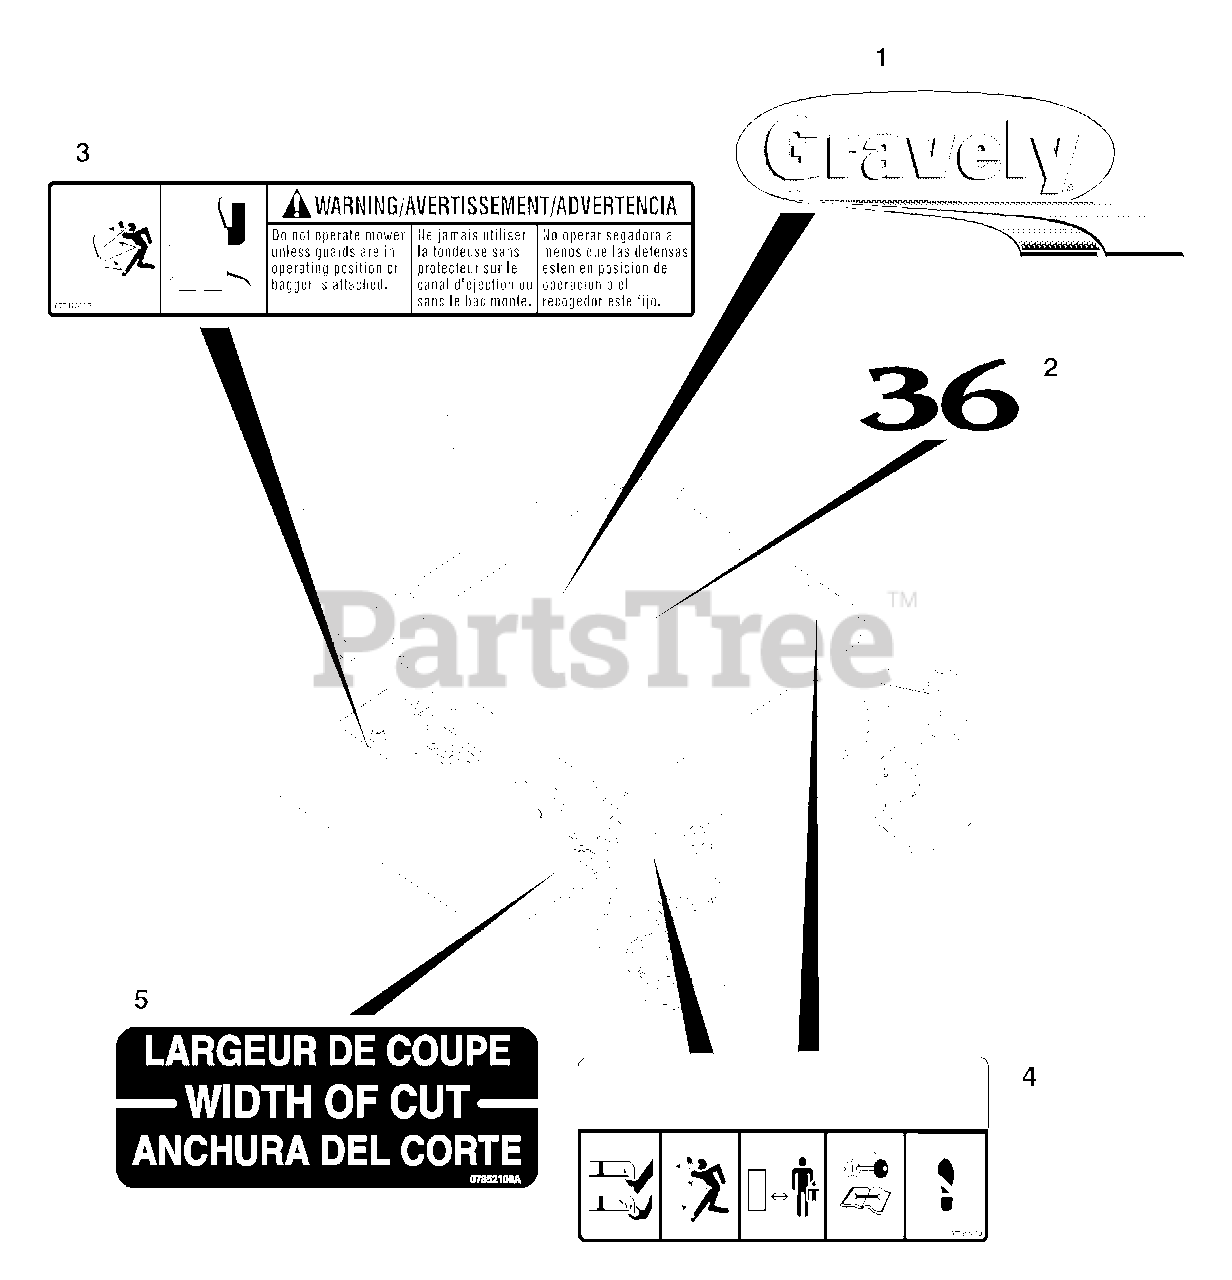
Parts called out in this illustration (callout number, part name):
1	Decal, Gravely Logo
2	Decal, 36
3	Decal, Warning
4	Decal, Mower Pan Head Danger
5	Decal, Width of Cut
